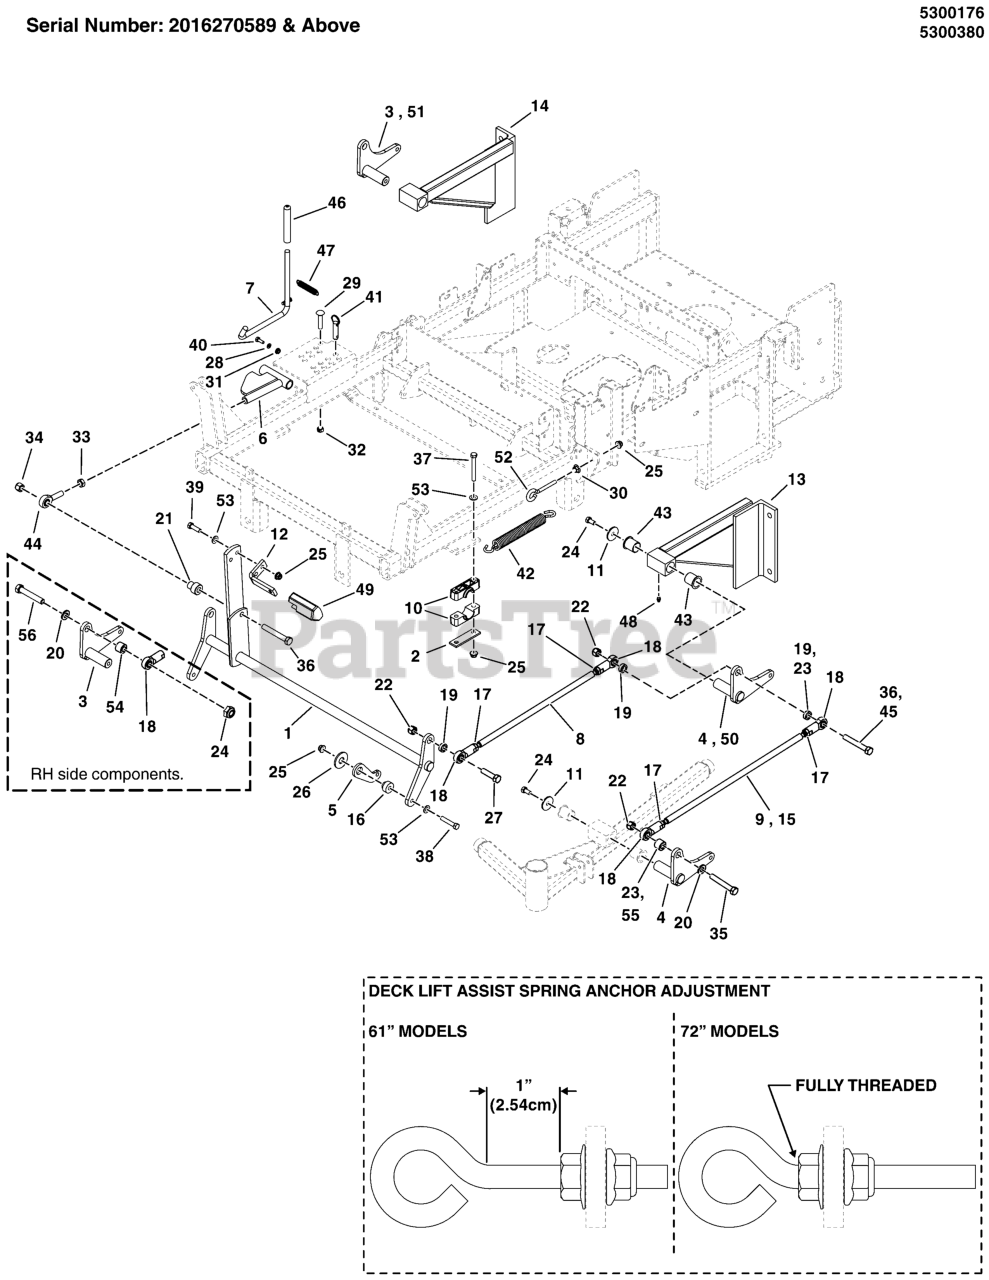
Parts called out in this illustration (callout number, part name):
1	WELD, DECK LIFT SHAFT IS3100Z - RED
2	PLATE, PIVOT BLOCK SUPPORT - BLK
3	WELD,DECK LIFT LEVER,RH
4	WELD, DECK LIFT LEVER, LH
5	LINK, SPRING, IS3100Z - RED
6	WELD, DECK ADJUST LINK - RED
7	WELD, DECK LIFT CONTROL, IS3000 - BLK
8	ROD, DECK LIFT, EXTERNAL THRD, 20.63
9	ROD, DECK LIFT, EXTERNAL THRD, 23.38
10	PIVOT BLOCK, PLASTIC
11	WASHER, .390 X 1.50 X .109, YZ
12	PEDAL, FOOT - BLK
13	WELD, LIFT FRAME, LH
14	WELD, LIFT FRAME, RH
15	ROD, DECK LIFT, EXTERNAL THRD, 26.13
16	BUSHING, DECK PIVOT
17	NUT, 1/2-20 HEX JAM
18	JOINT-BALL .500-20 THD .500ID, CLR ZINC
19	SPACER, .56 X .90 X .31
20	WASHER, 1/2 GD9 YZ
21	ADAPTER, CASTER AXLE, CZ
22	NUT, 1/2-13 HEX NYLON LOCK
23	SPACER, .52 X 1.00 X .75, CZ
24	BOLT, 3/8-16 X 3/4, PLT W/PATCH
25	NUT, 3/8-16 HEX NYLOCK FLANGE
26	WASHER, .39 X 2.00 X X .14
27	BOLT, 1/2-13 X 2" GD5 CZ
28	WASHER, 1/4 SAE
29	BOLT, 3/8-16 X 2, CARRIAGE
30	NUT, 3/8-16 HEX SERRATED FLANGE
31	NUT, 1/4-20 HEX SERR. FLANGE
32	NUT, 3/8-16 HEX SIDE LOCK
33	NUT, 1/2-20 HEX JAM
34	NUT, 1/2-13 HEX NYLON LOCK
35	BOLT, 1/2-13 X 2-1/2" GD5 CZ
36	BOLT, 1/2-13 X 3-1/2, HEX HD, GD5, CZ (SV)
37	BOLT, 3/8-16 X 3" GD5 CZ
38	BOLT, 3/8-16 X 2, GD5, CZ
39	BOLT, 3/8-16 X 1-1/4" GD5 CZ
40	BOLT, 1/4-20 X 3/4 GD5 YZ
41	PIN, HITCH, 1/2 X 2.00 OAL, YP
42	SPRING-EXT, 1.00 ODX13.25LGX.177WR, BLK
43	BUSHING, 1.00 X 1.13 X 1.38, PLASTIC
44	BALL JOINT, 1/2-20, MALE
45	BOLT, 1/2-13 X 3" GD5 CZ
46	GRIP, FOAM, .475 X 4.35 X .095
47	SPRING-EXT, .500 OD X 3.50 LG X .058 WR
48	GREASE FITTING, 1/4-28 STRAIGHT
49	PEDAL, Rubber
50	WELD, DECK LIFT LEVER, LH - BLK
51	WELD, DECK LIFT LEVER, RH - BLK
52	EYE BOLT, 3/8-16 X 2-1/2
53	WASHER, 3/8 SAE
54	SPACER, .52 X 1.0 X .875
55	SPACER, .52 X 1.0 X .625
56	BOLT, 1/2-13 X 2-3/4 GD5 CZ
